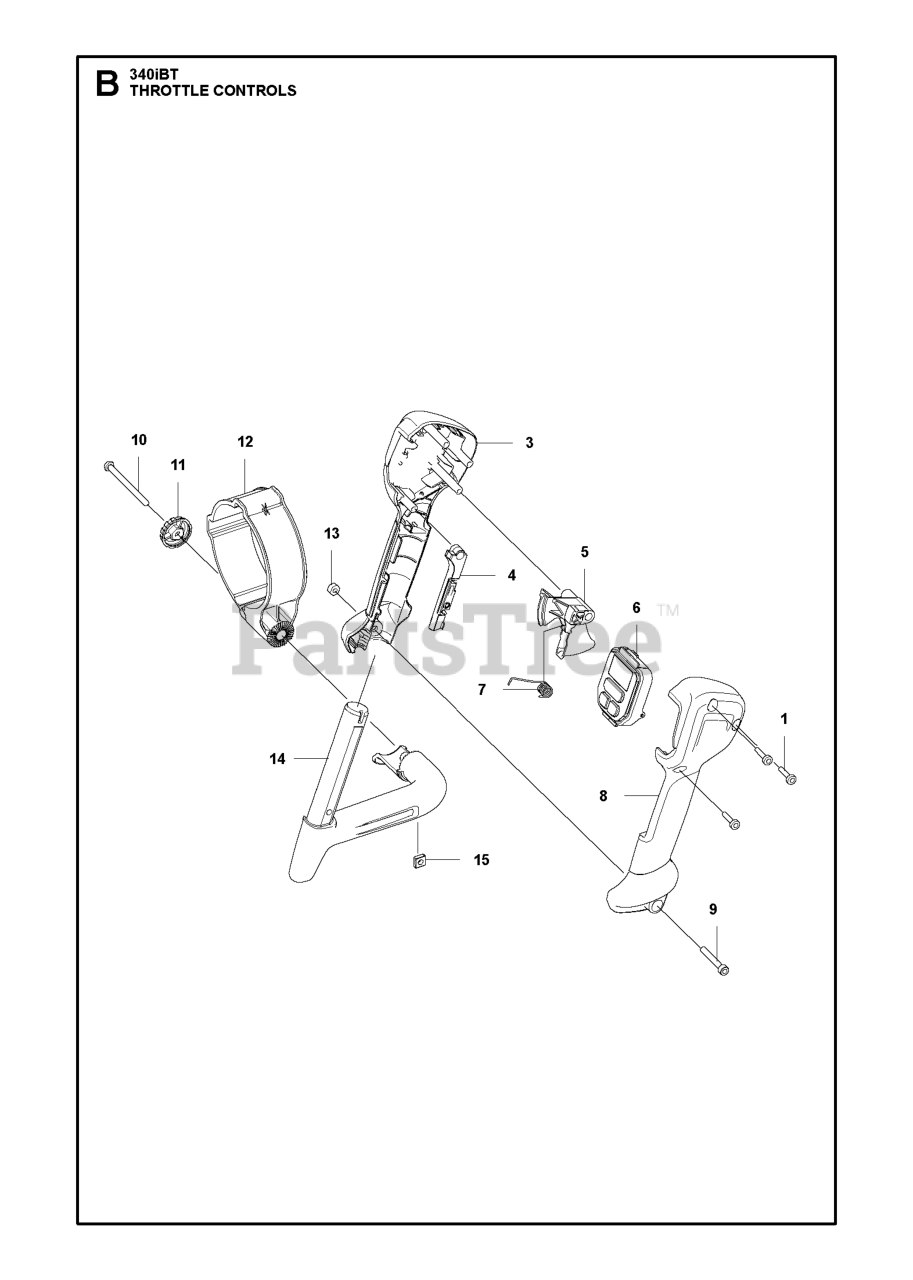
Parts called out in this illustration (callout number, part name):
1	SCREW ITXSCT PW4.2X18 10.9 ZN
4	COVER HANDLE ESD
5	THROTTLE CONTROL ASSY
7	SPRING THROTTLE CONTROL
8	HANDLE HALF RIGHT
12	HANDLE HOLDER
14	HOLDER HANDLE
